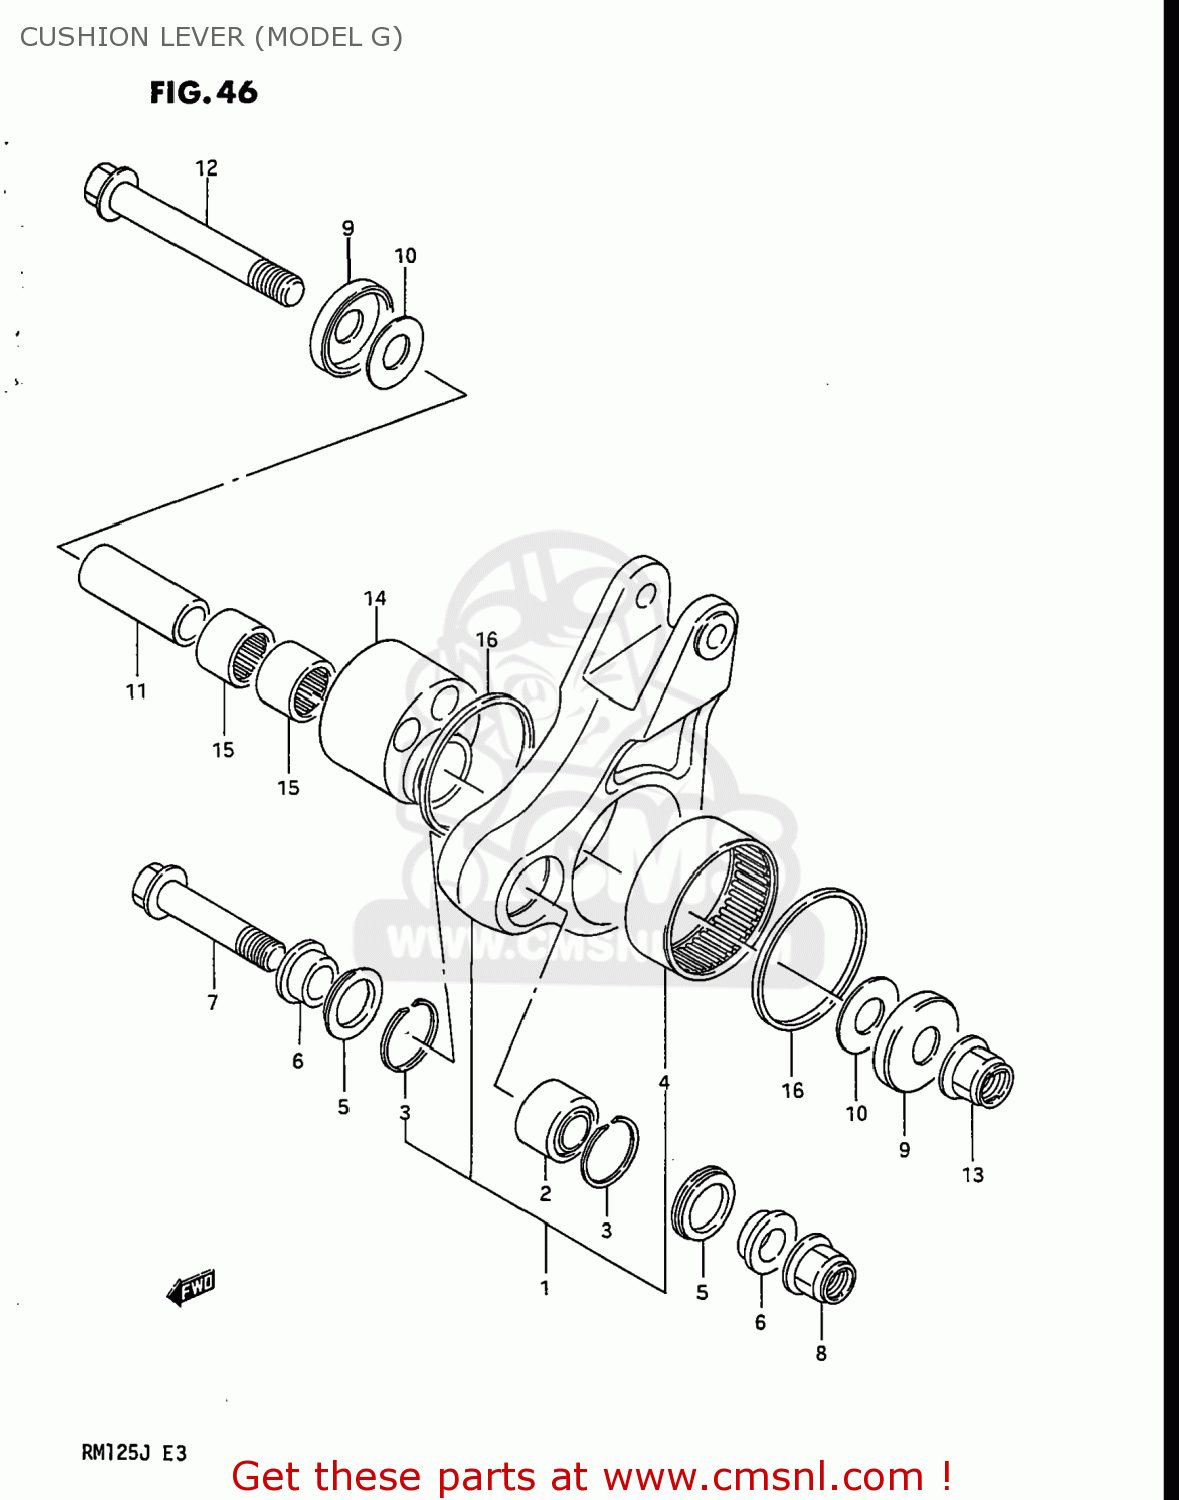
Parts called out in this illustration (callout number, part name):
1	LEVER SET,REAR CUSHION
2	SPHERICAL BEARING (14X3)
3	RING,STOPPER
4	BEARING 55X63X25
5	DUST SEAL,REAR CUSHION,LEFT
6	SPACER,REAR CUSHION LEVER
7	BOLT,RR CUSHION LEVER FR
8	NUT
9	DUST SEAL,RR C
10	WASHER
11	SPACER,RR CUSHION LEVER CTR
12	SHAFT,RR CUSHION LEVER
13	NUT
14	SPACER,RR CUSHION ECCENTRIC
15	BEARING
16	SEAL,REAR CUSHION LEVER
